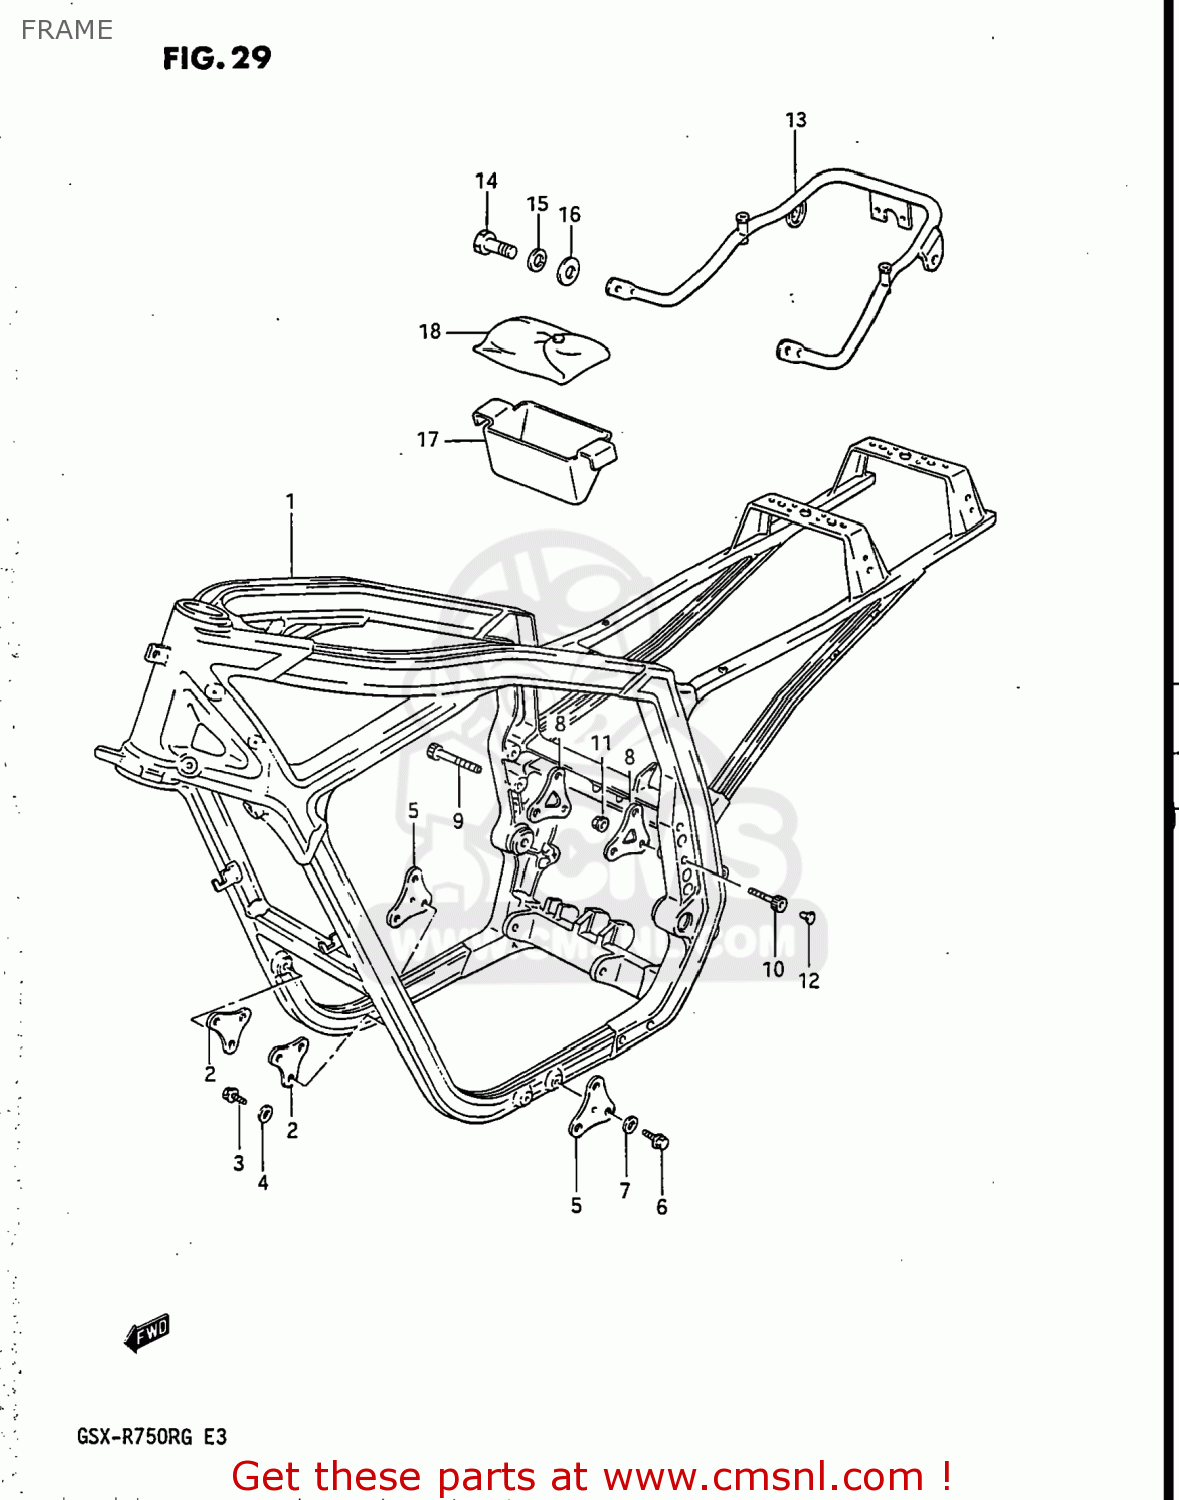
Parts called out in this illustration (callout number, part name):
1	FRAME
2	PLATE,ENGINE MOUNTING NO
3	BOLT
4	WASHER (8.2X20X1.6)
5	PLATE,ENGINE MOUNTING NO.1
6	BOLT
7	WASHER (8.2X20X1.6)
8	PLATE,ENGINE MOUNTING NO
9	BOLT
10	BOLT, RH
11	NUT
12	CAP,ENGINE MOUNTING
13	GRIP COMP,REAR
14	BOLT
15	WASHER,LOCK
16	WASHER
17	HOLDER,TOOL
18	TOOL ASSY
